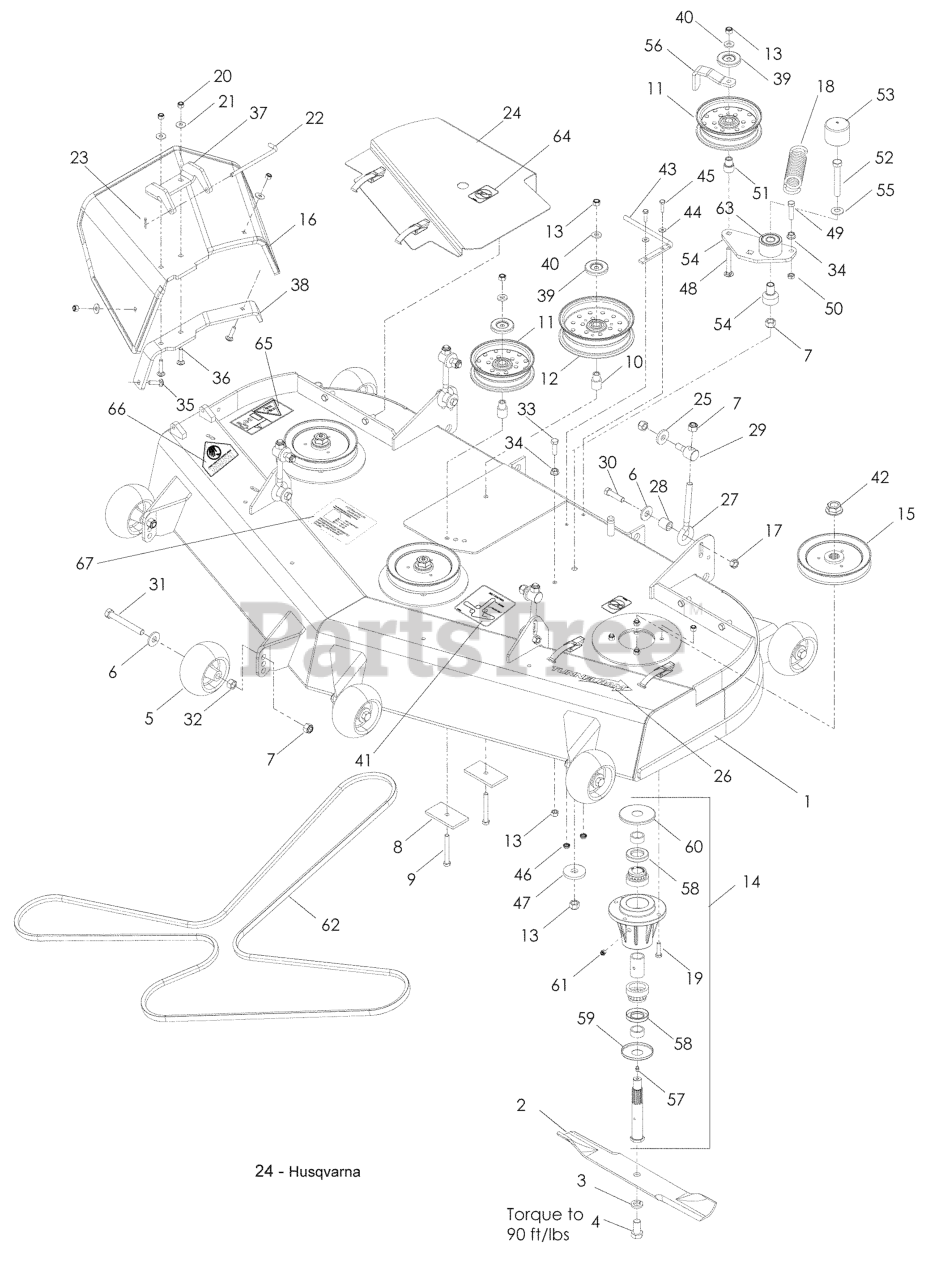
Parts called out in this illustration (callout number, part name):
1	DECK W/DECALS 61" HUS
2	BLADE OEM 21" (61" DECK)
3	LOCKWASHER 5/8
4	HCS 5/8F X 1 1/4
5	GAUGE WHEEL
6	WASH USS FLAT 1/2
7	NUT 1/2-13 HEX NYLOC ZD
8	SUPPORT PLATE
9	HCS 3/8C X 3
10	IDLER BUSHING
11	IDLER PULLEY
12	PULLEY - IDLER, 6IN WIDE
13	NUT 3/8-16 NYLOC
14	HOUSING ASM, 52/61
15	PULLEY, 61
16	CHUTE, RUBBER DISCHARGE 52/61"
17	NUT 7/16C CENTERLOCK
19	HCS 5/16C X 1 1/4
20	NUT 5/16 NYLOC
21	WASHER 5/16 FLAT
22	PIN, CHUTE PIVOT
23	RP_COTTER PIN 1/8 X 3/4
24	SUB ASM, 61 BELT SHIELD RH
25	WASHER-.533IDX1.37OD
26	DECAL, TUNNEL RAM 8"
29	SWIVEL, DECK HEIGHT ADJ
30	HCS 7/16 - 14 X 1 3/4
31	HCS 1/2-13 X 4 GR 5 ZD
32	NUT HEX 1/2
33	HCS 3/8C X 1 1/4 GR5
34	NUT 3/8C WHIZ
35	BOLT, CARRIAGE 5/16X1-1/4
36	RHSNB 5/16-18 X 1-1/2 GR 5 ZD
37	PIVOT BRACKET - RUBBER CHUTE
38	BRACKET, REINF-CHUTE
39	DUST SHIELD
40	WASHER, 3/8 THICK
41	DECAL, BELT ROUTING
42	NUT FLANGE 3/4-16
43	BELT GUIDE
44	WASHER 1/2 FLAT
45	HCS 1/4 X 1
46	NUT 1/4-20 HEX FLG LK ZD
47	WASHER, SUPPORT
48	RHSNB 3/8-16 X 2.75
49	HCS 3/8-16 X 1-1/2
50	NUT 3/8-16 HEX JAM
51	BUSHING, IDLER
52	HCS 1/2C X 3 1/4
53	CAP, VINYL
54	PIVOT, BEARING
55	CONTACT BELLSPR 1/2
56	GUIDE, BELT
57	ZERK
58	SHAFT SEAL
59	BOTTOM DUST CAP
60	TOP DUST CAP
61	PLUG-VENTED
62	BELT, DECK 61
63	ARM-IDLER W/BRG
64	DECAL, NO STEP
65	DECAL, EURO SEVERING
66	DECAL, CPSC
67	DECAL, ANTI SCALP
